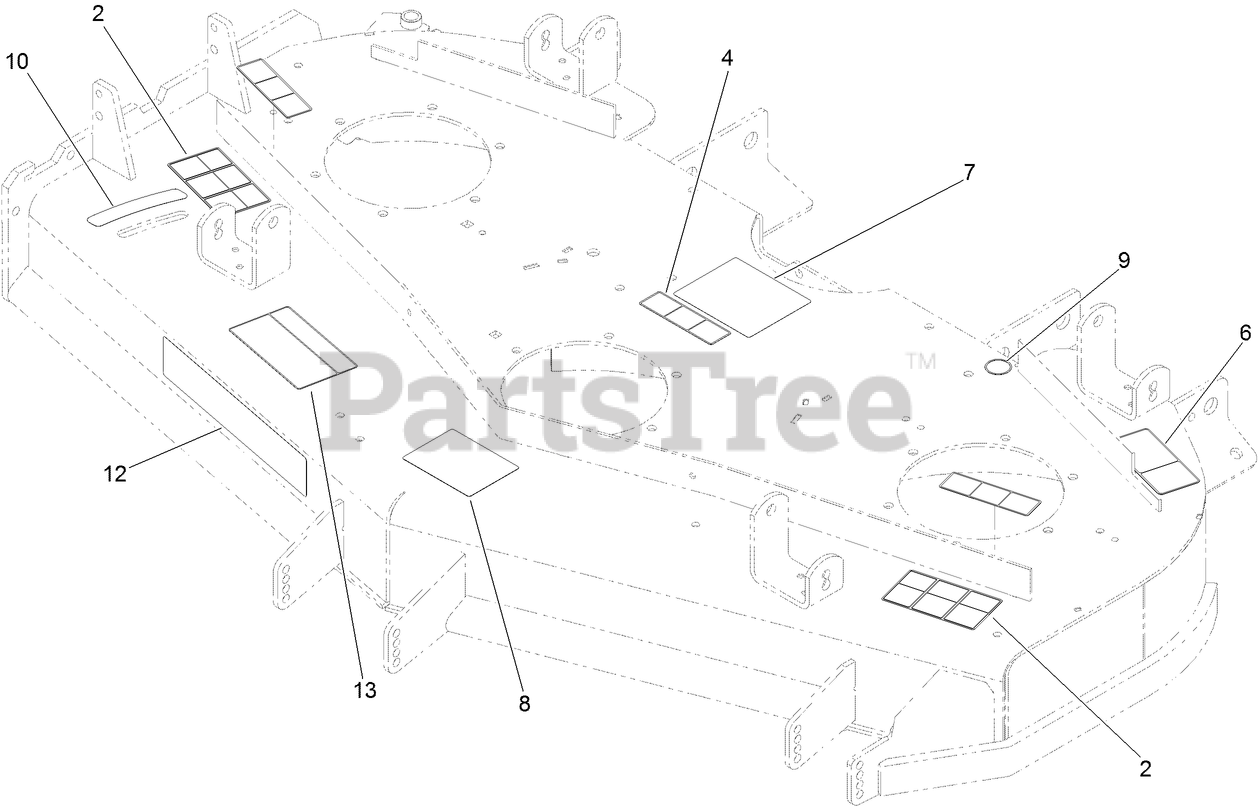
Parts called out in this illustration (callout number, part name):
2	DECAL-DANGER
4	DECAL-COVER, MISSING
6	DECAL-TORQUE, BLADE BOLT
7	DECAL-ROUTING, BELT
8	DECAL-SCALP, ANTI
9	DECAL-GREASE
10	DECAL-SETTING, BAFFLE
13	DECAL-ADJUSTMENT, BAFFLE
